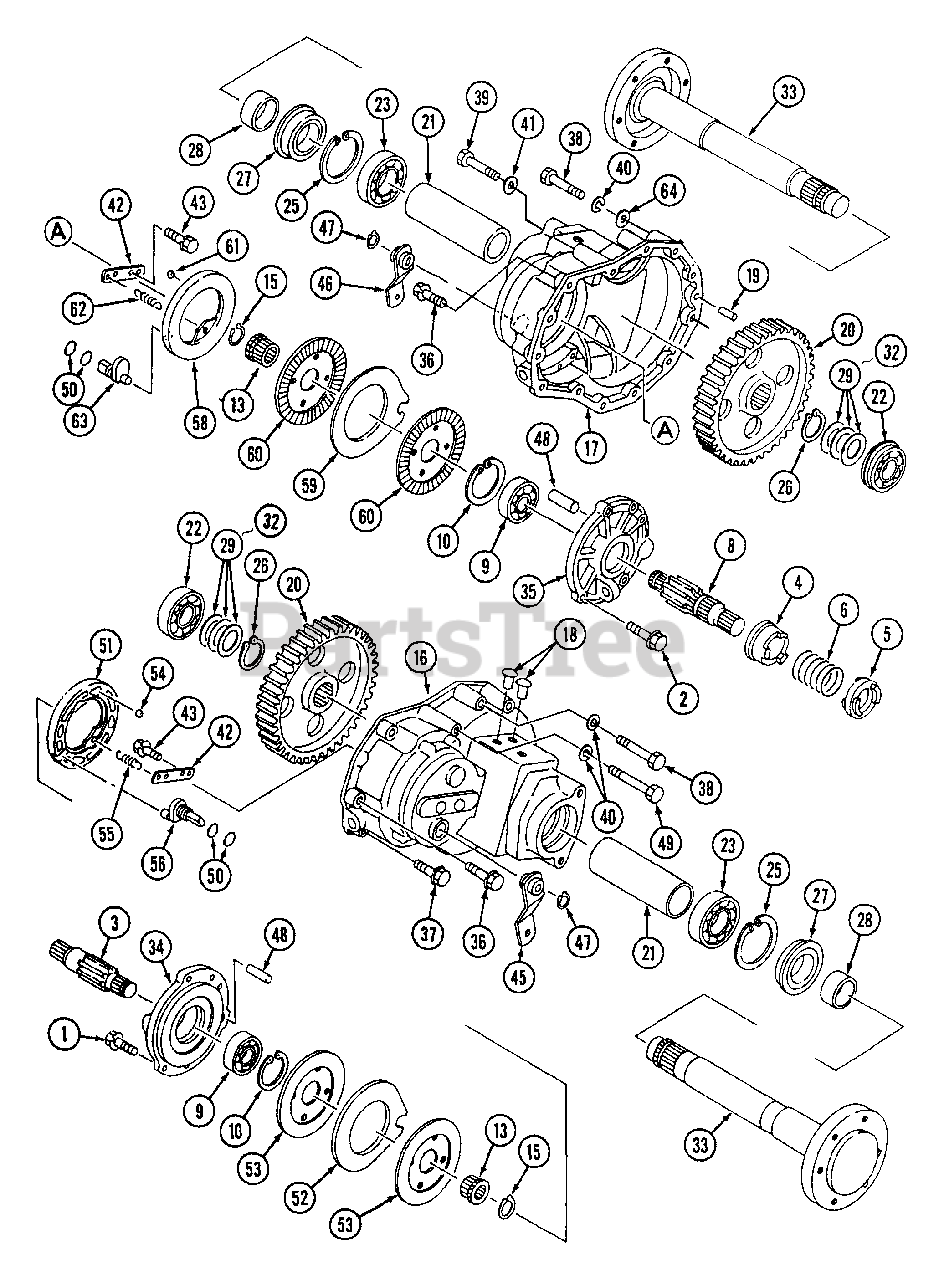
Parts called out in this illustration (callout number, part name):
29	Shim Set
45	Lever, Brake L.H.
46	Lever, Brake R.H.
52	Plate, Mating
55	Spring, Return
59	Plate, Mating
62	Spring, Return
